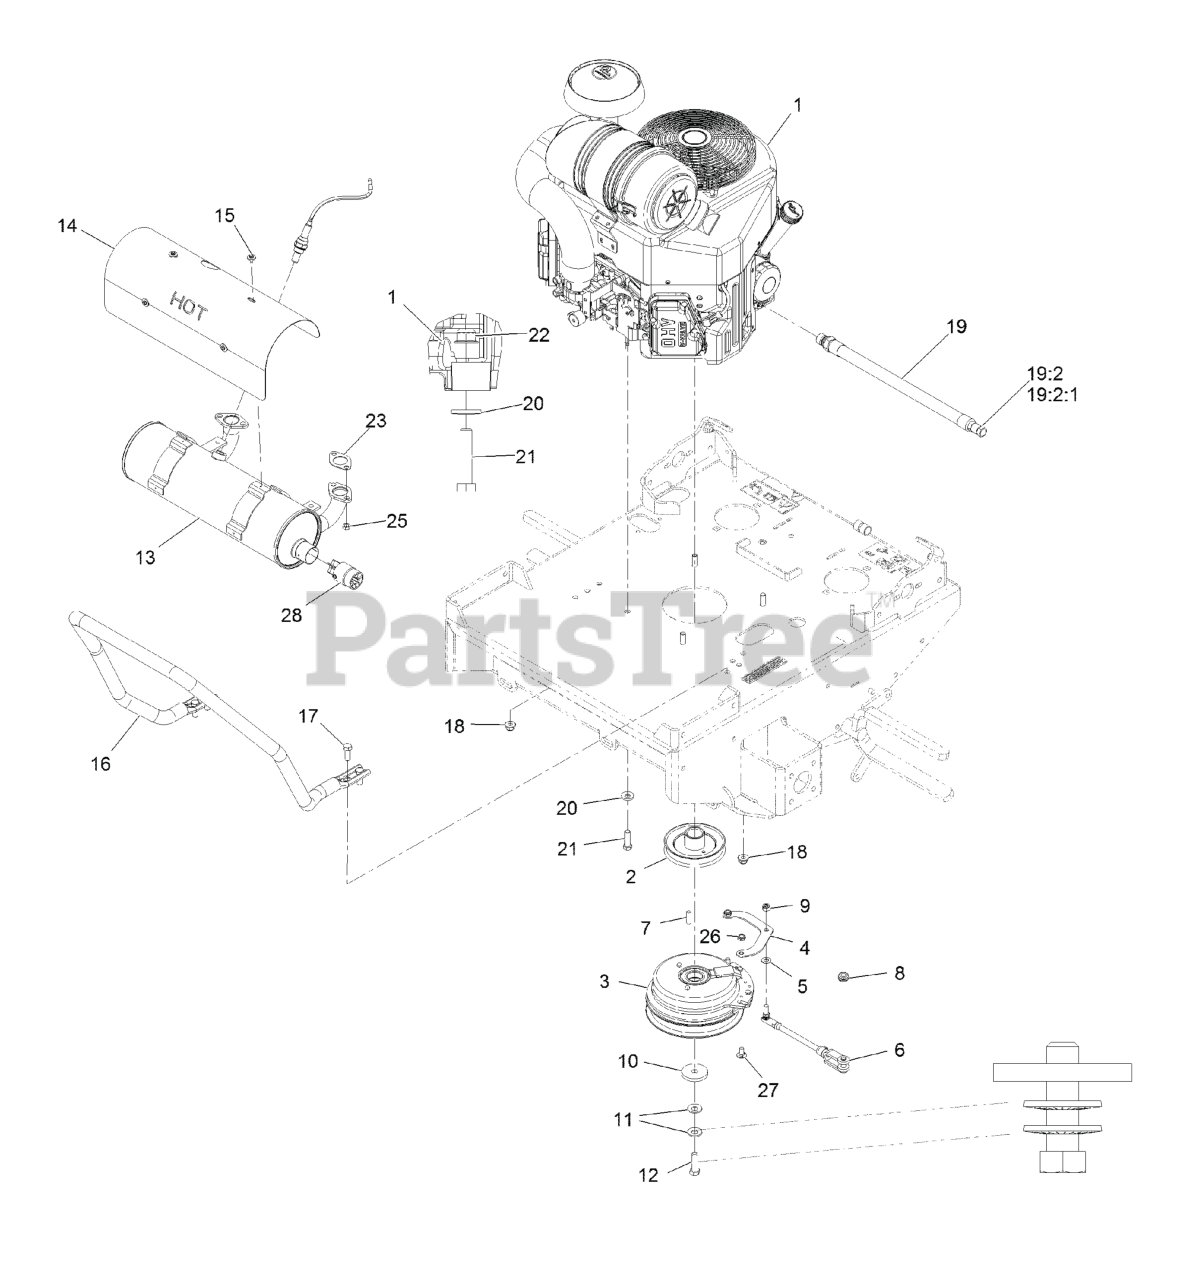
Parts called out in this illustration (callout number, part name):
2	SHEAVE W/ HUB
3	CLUTCH, 200 FT/LBS, 1.13
4	STRAP, CLUTCH
5	WASHER-PLAIN
6	ASM, CLUTCH ANCHOR
7	KEY
8	GROMMET
9	NUT-LOCK
10	WASHER-CLUTCH
11	WASHER-SPRING
12	BOLT-HEX, TAP
13	MUFFLER-TTX, EFI
14	SHIELD-MUFFLER,TTX EFI
15	SCREW-HH, THREAD FORMING
16	Guard,Air Cleaner
17	SCREW-HH
18	NUT-HF, NI
19	OIL DRAIN HOSE ASM
19:2	PLUG-HH
19:2:1	O-RING
20	WASHER-SPRING
21	SCREW-HH
22	NUT-HF, NI
23	GASKET-EXHAUST
25	NUT-FLANGE
26	NUT-LOCK, NI
27	SCREW-CARR
28	SCREEN-ARRESTER, SPARK
